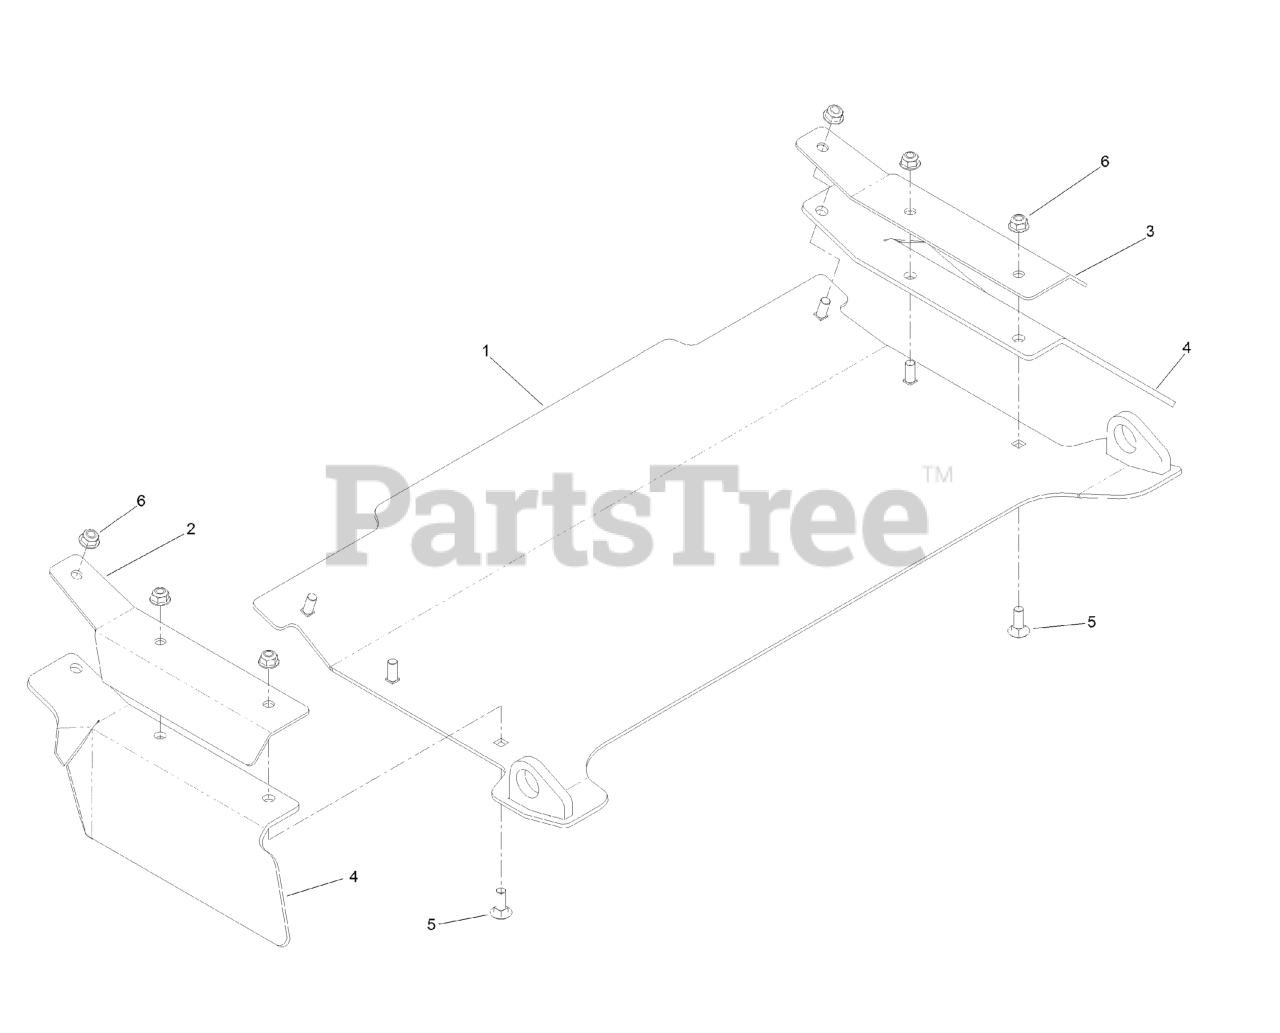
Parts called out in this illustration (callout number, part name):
1	DISCHARGE TUNNEL ASM
2	BRACKET-FLAP, LH
3	BRACKET-FLAP, RH
4	FLAP-RUBBER
5	SCREW-CARR
6	NUT-HF, NI
